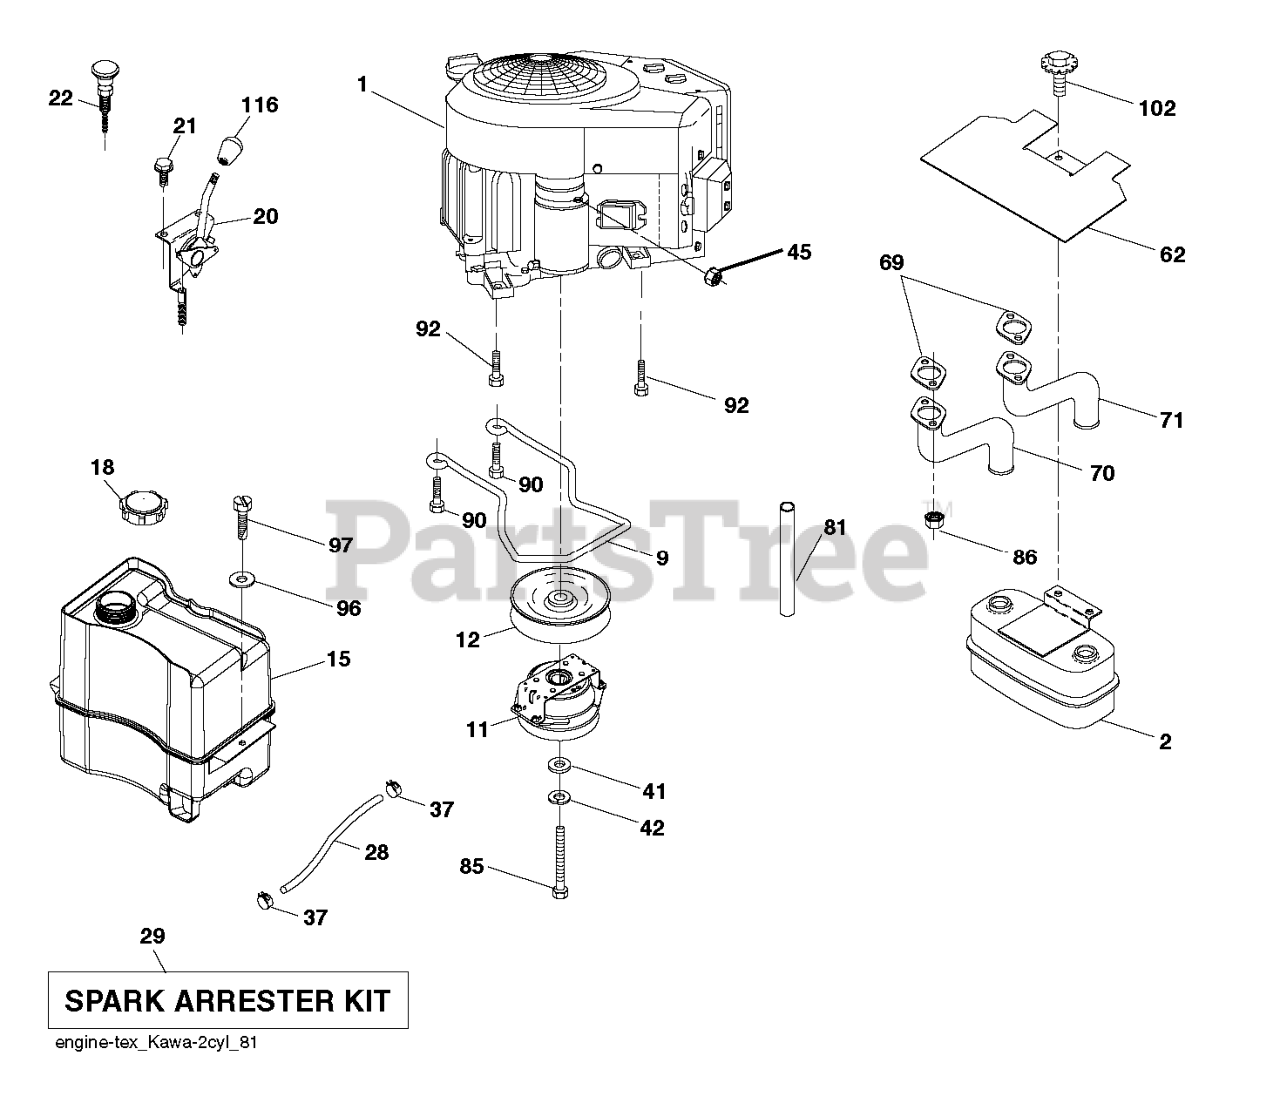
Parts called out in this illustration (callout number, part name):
2	MUFFLER.ASM.TWIN.MNTG.BRACKET
9	KEEPER.BELT.ENG.4.25"2.BLT.431
11	CLUTCH MAGNETIC CLUTCH & BRAKE
12	PULLEY.ENGINE.TUFFTORQ
15	TANK.ASSEMBL.2.5GAL.NON-EPA
18	CAP ASM.FUEL.2.25"FR.
20	CONTROL.THROTTLE.PRO.
22	CONTROL, CHOKE
28	LINE.FUEL.20
29	KIT.SPARK ARRESTOR 794945 B&S
37	HOSE CLAMP
62	SHIELD.HEAT.MUFFLER
70	TUBE.EXHAUST.LH.FR961/FR730
71	TUBE.EXHAUST.RH.FR961/FR730
81	TUBE, DRAIN OIL ASM.
85	BOLT.HEX.7/16-20X3.75.GR5.RED
86	NUT.HEX.FLANGE.TOPLOCK
90	SCREW 3/8-16X1
92	SCREW 3/8-16X1
97	SCREW HEXWSHR 1/4-20X3/4
102	SCREW
116	KNOB - SHIFT
